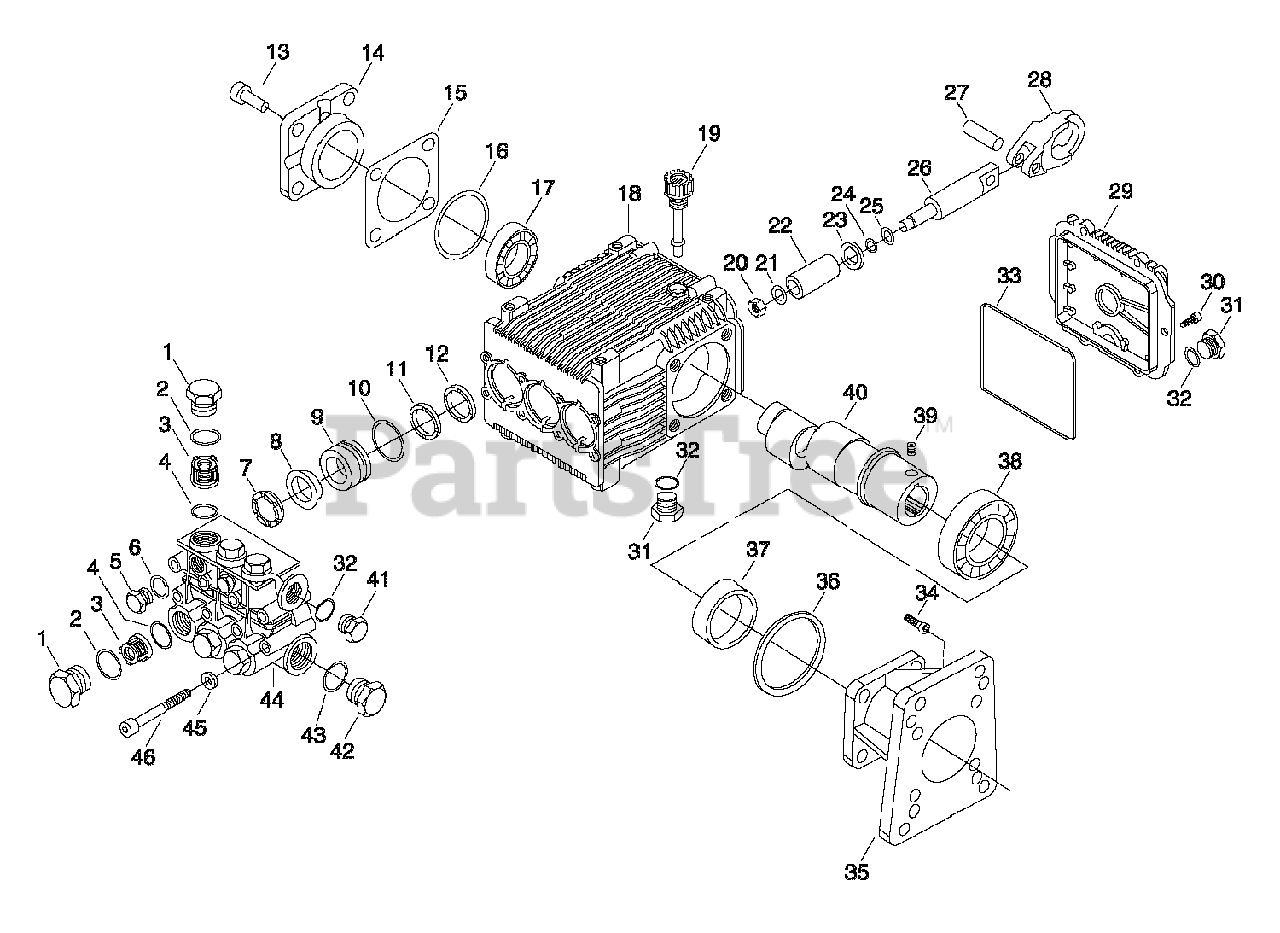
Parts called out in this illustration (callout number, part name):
4	O-Ring
6	O-Ring
7	Support Ring
9	Piston Guide
14	Bearing Support
16	O-Ring
18	Pump Housing
19	Oil Cap
26	Piston Guide
27	Piston Pin
34	Screw
39	Grub Screw
44	Pump Head
47	Thermal Relief Valve
